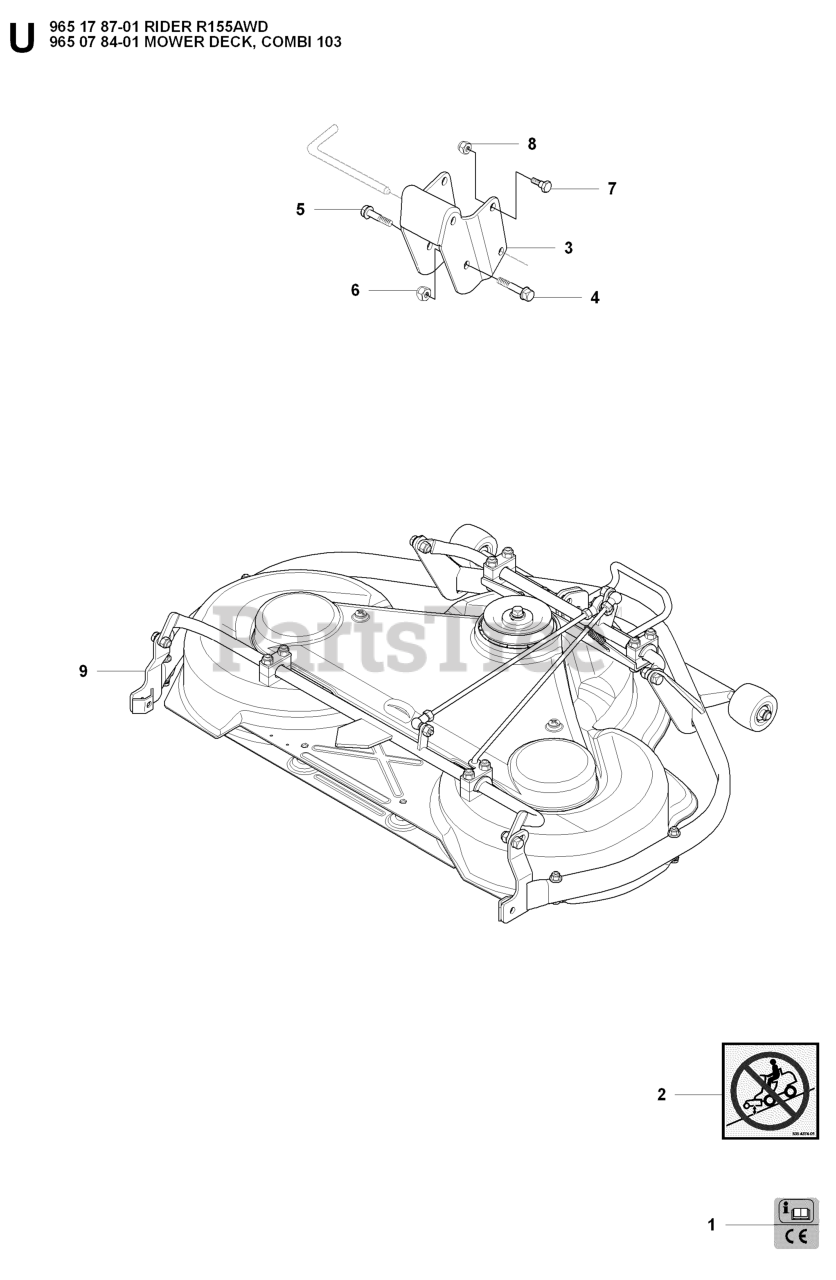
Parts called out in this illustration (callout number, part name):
5	Hex Head Capscrew, M12 X 1.75 X 30 DIN933ZP
8	LOCKNUT M8
9	DECK COMBI 103
